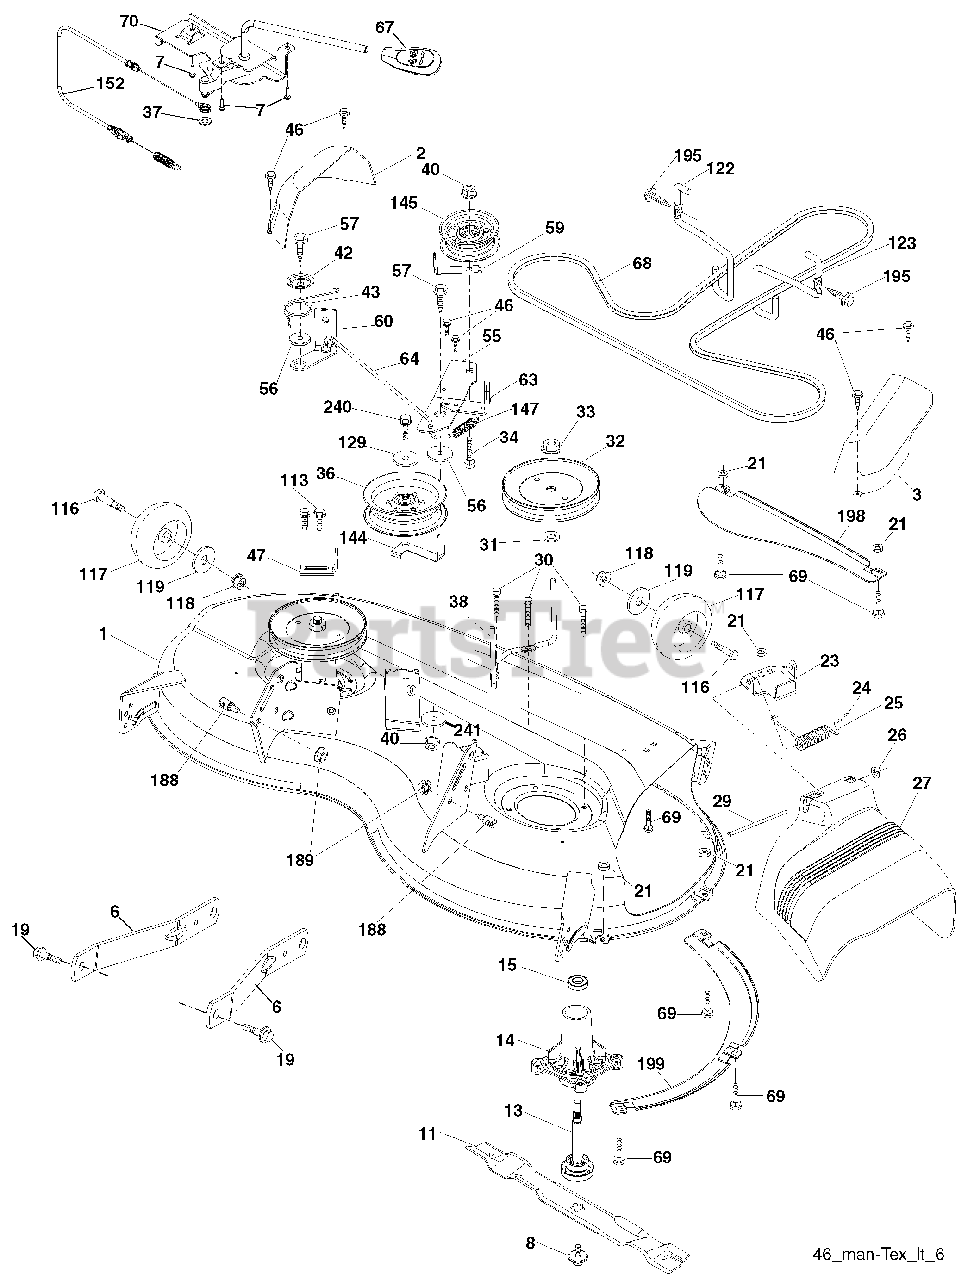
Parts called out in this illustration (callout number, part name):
1	Mower Housing
2	Cover Mandrel LH
3	Cover Mandrel RH
6	Arm Suspension
7	Screw 10 x 3/4 Single Hex
8	Bolt/Washer Asm 7/16-20 unf
11	Blade, 46" Hi-Lift (For bagging or discharge)
13	Shaft Assembly, Mandrel
14	Housing, Mandrel
15	Bearing, Ball, Mandrel
19	Bolt, Shoulder
21	Nut, Crownlock 5/16-18 unc
23	Bracket, Deflector
24	Cap, Sleeve
25	Spring, Torsion, Deflector
26	Nut, Push
27	Shield, Deflector
29	Rod, Hinge
30	Screw Thdrol Rolling Wsh Hd
31	Washer, Spacer
32	Pulley, Mandrel
33	Nut, Toplock, Flanged
34	Bolt Carr Sh. 3/8-16 x 1-1/2 Gr. 5
36	Pulley, Idler, Flat
37	Washer 13/32 x 13/16 x 16 Ga.
38	Keeper Belt LH Mandrel
40	Nut, Lock Flg. 3/8-16 unc
42	Spring Torsion Brake
43	Spring Torsion Retainer
46	Screw Thd Roll 1/4-20 x 5/8
47	Bracket Clutch Cable
55	Arm, Idler
56	Spacer, Retainer
57	Screw Hexwsh Thd 3/8-16 x 1
59	Guard, Tuv Idler (94)
60	Arm Brake Mower
63	Arm Brake Mower
64	Linkage Brake
67	Handle, Clutch Cable
68	V-Belt
69	Bolt Rdhd Sqnk 5/16-18 x 5/8
70	Clutch Asm. Manual
113	Screw 5/16-18
116	Bolt SHLD
117	Wheel Gauge
118	Nut Centerlock 3/8-16 unc
119	Washer 3/8 x 7/8 x 14 Ga.
122	Keeper Belt Eng. LH
123	Keeper Belt Eng. RH
129	Washer 13/32 x 13/16 x 12 Ga.
144	Keeper Belt
145	Pulley Idler
147	Spring Return
152	Cable Clutch Manual w/Spr.
188	Stud Fastener
189	Nut Lock Hex Flange
195	Screw Hexwsh Thdr 3/8-16 x 3/4
198	Baffle Center Front
199	Baffle Front RH
240	Bolt Fin Hex 3/8-16 x 2-1/4 Gr. 5
241	Washer 13/32 x 2 x 10 Ga.
241	Mandrel Assembly
241	Replacement Mower, Complete
